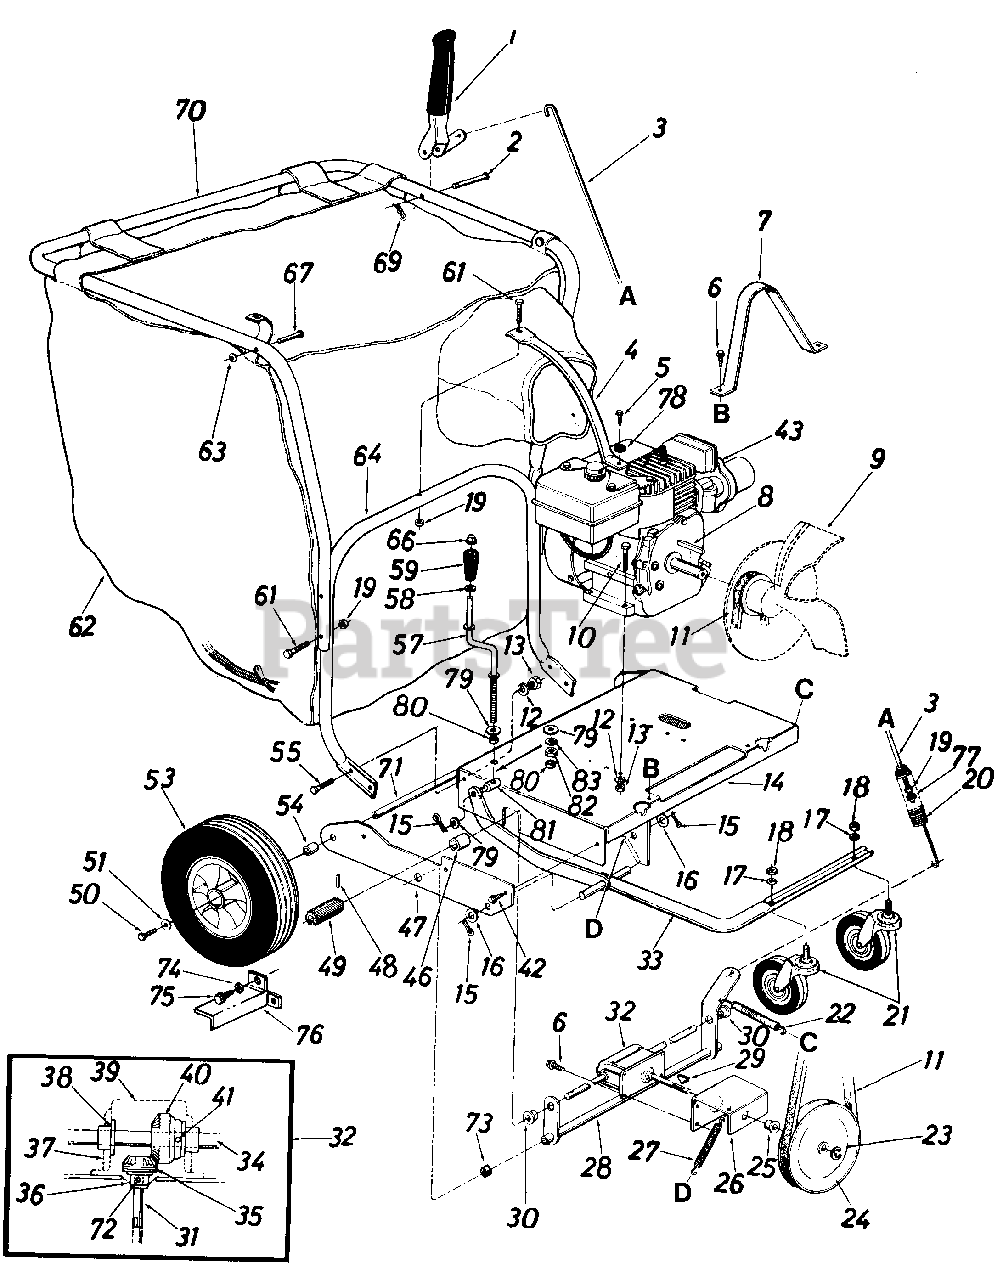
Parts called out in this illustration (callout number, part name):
1	Clutch Grip Ass'y.
2	Clevis Pin .375" Dia. x 1.88"
3	Clutch Rod 32" Lg.i
4	Handle Brace (Painted)
5	Part of Engine
6	Hex L.-Wash. Hd. B Tap Scr. 1/4" x .62" Lg.
11	"V"-Belt
12	L.-Wash. 5/16" I.D.
13	Hex Nut 5/16-18 Thd.*
16	Fl.-Wash. .63" I.D. x 1.25" O.D.
17	L.-Wash. 1/2" I.D.*
18	Hex Nut 1/2-13 Thd.*
19	Hex Cent. L.-Nut 1/4-20 Thd.
20	Extension Spring .78" O.D. x.75" Lg.
21	Swivel Caster Wheel 5" Dia. x 1.25"
22	Extension Spring .38" O.D. x 7.50" Lg.
23	Snap"E"-Ring .50" Dia. Shaft
24	"V"-Pulley 5/8" x 6.50" O.D.
25	Flange Bearing .502" I.D.
28	Clutch Bracket Ass'y.
29	#2 Woodruff Key 3/32" Dia. x .81" Lg.
30	Hex Flange Bearing Bronze .625" I.D.
31	Pinion Shaft .50" Dia. x5.0"
32	Gear Box Ass'y. Comp.
35	Bevel Gear .50" I.D. x 14 Teeth
36	Flange Bearing .503" I.D.
37	Gear Box
38	Flange Bearing .630" I.D.
39	Gear Box Cover
40	Bevel Gear .62" I.D. x 28 Teeth
41	Spring Pin Spiral 3/16" Dia. x 1.25" Lg.
42	Hex Wash. Hd. "AB" Tap Scr. 5/16" x .75" Lg.
43	Engine
46	Spacer .63 I.D. x .88" O.D. x .56" Lg.
49	Drive Pinion
50	Hex Locking Bolt 5/16-24 x .62" Lg.
51	Fl.-Wash. .34" I.D. x .87" O.D.
53	Wheel Ass'y.-Comp. 12" x 3" Incl. Ball Bearings)
54	Spacer .63" I.D. x 1.0" O.D. x .94" Lg.
55	Hex Bolt 5/16-18 x .75" 4.*
57	Height Adjustment Crank
58	Fl.-Wash. .385" I.D. x .62" O.C
59	Crank Knob
61	Hex Bolt 1/4-20 x 1.75" 4.
62	Vacuum Bag - Felt
63	Push Speed Nut .25" Dia. Stud
66	Push Nut 3/8" Dia.
67	Stud Pin .250" Dia. x 1.75"
69	Internal Cotter Pin 3/8" Dia.
70	Upper Handle (Painted)
71	Rear Axle .624" Dia. x 24.37'
72	Spring Roll Pin 5/32" Dia. x 1.12
73	Spacer .82" I.D. x 1.0" O.D. x .305 Lg.
74	L.-Wash. .265" I.D.
75	Hex Self Tap Scr. 1/4" x 3/8" Lg.
78	Belleville Washer
79	Fl.-Wash. .35" I.D. x .87" QD.
80	Spacer .38" I.D. x .50" O.D. x .180" L.g
81	Ferrule 3/8-8 x .38" Dia.
82	Hex Nut 3/8-8 Thd.
83	L.-Wash. 3/8" I.D.
